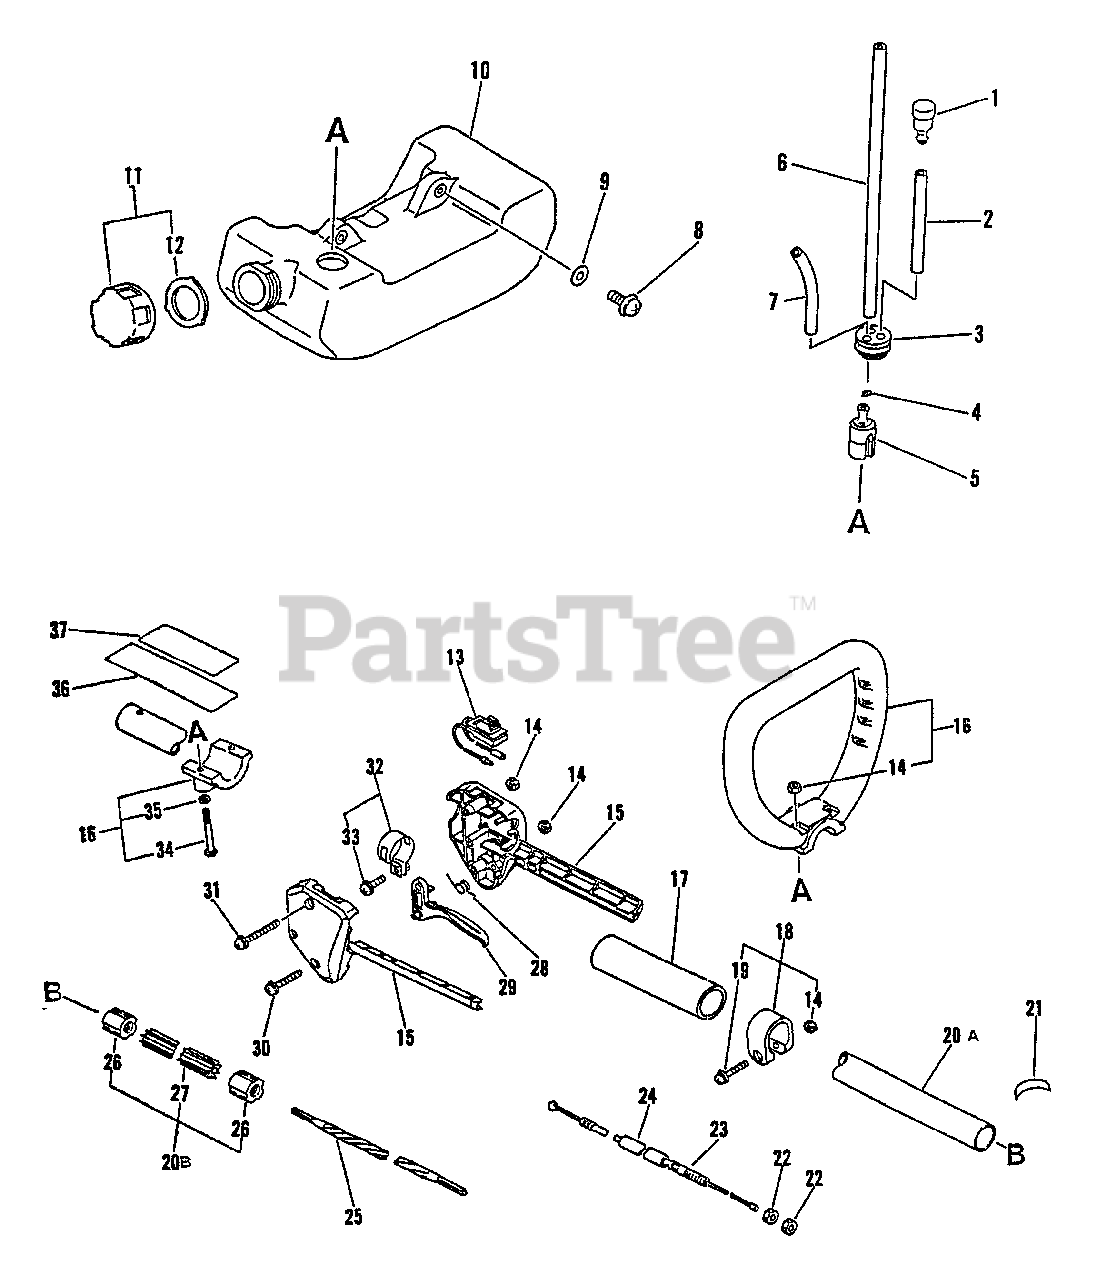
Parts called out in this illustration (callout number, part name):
1	VENT ASSY
2	PIPE K43B3×5×70
3	GROMMET, FUEL Ø5
4	CLIP 6 MM
5	FILTER, FUEL
6	PIPE, FUEL
7	PIPE 3×5×90
8	SCREW 5×16
9	TANK, FUEL
10	CAP ASSY
11	CAP ASSY
12	GASKET, FUEL CAP
13	IGNITION SWITCH ASSY
14	NUT M5
15	HANDLE KIT, CONTROL
16	LOOP HANDLE ASSY
17	GRIP, HANDLE
18	CLAMP KIT
19	SCREW 5×30
20	MAIN PIPE ASSY 25×1500
21	LABEL - ALIGNMENT
23	CABLE, THROTTLE
25	DRIVESHAFT - FLEXIBLE L= 1522
27	LINER - FLEXIBLE
28	SPRING, TORSION
29	TRIGGER, THROTTLE
30	SCREW 5×25
31	SCREW 5×35
32	CLAMP KIT
33	SCREW 5×14
34	SCREW 5×40
35	WASHER, FLAT 5.5×10×0.8
36	LABEL - CAUTION
37	LABEL - CAUTION
